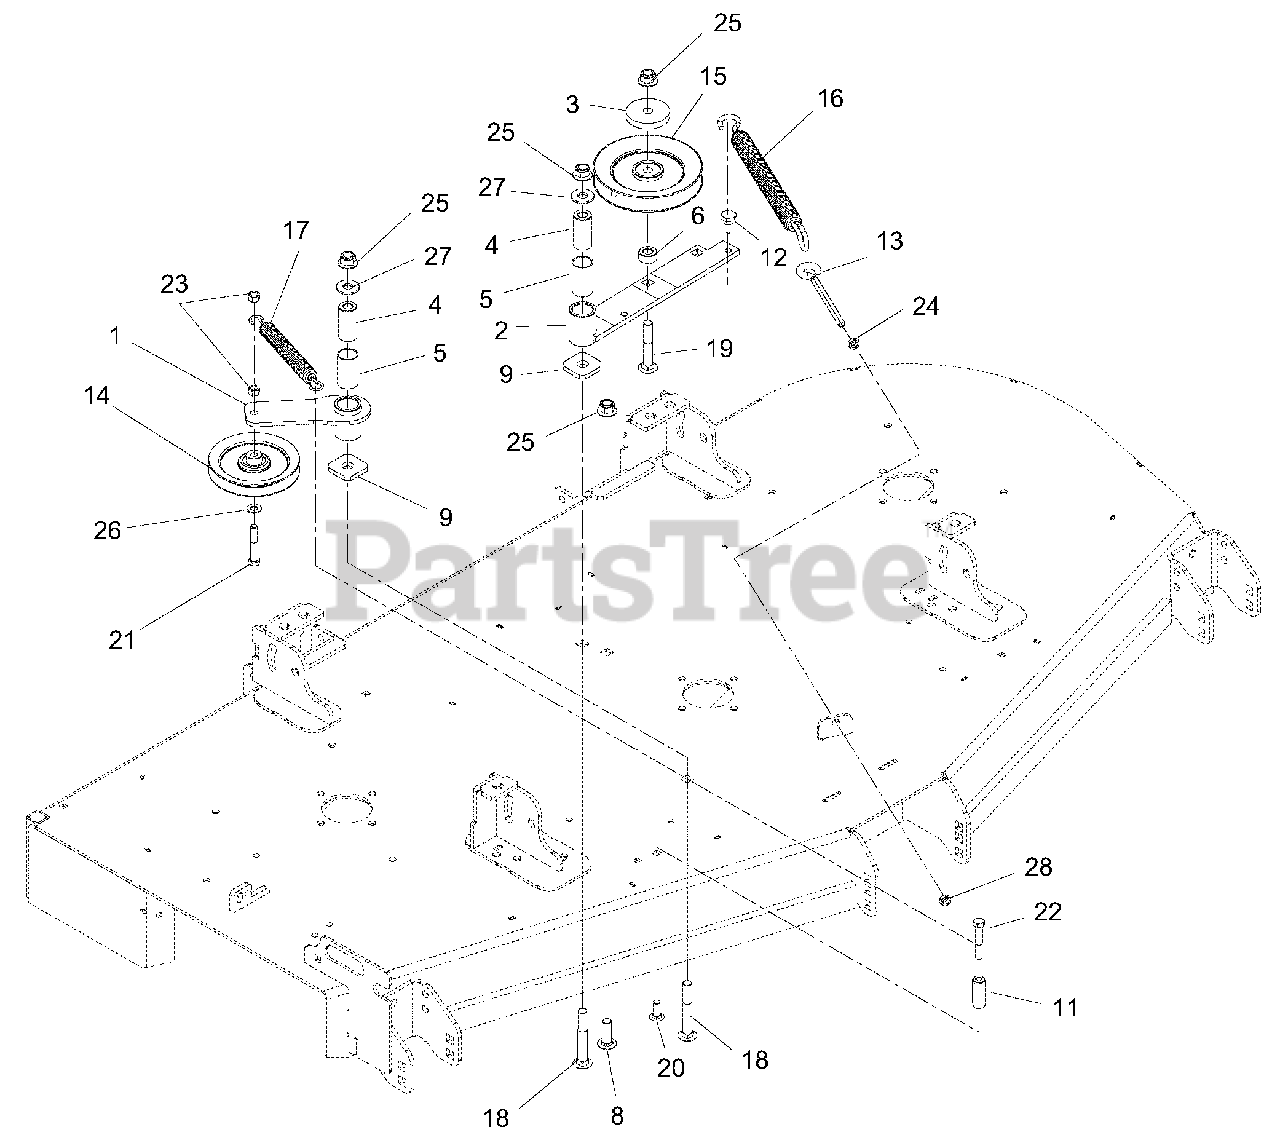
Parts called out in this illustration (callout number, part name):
1	WMT, IDLER PIVOT ARM
2	WMT, IDLER PIVOT ARM
3	CAP, IDLER BEARING SEALING
4	BSHG, SPCR .502X.997X2.03
5	BSHG, 1.00X1.125X1.937
6	BSHG, SPCR .502 X .997.50 PM
8	BLT, RNHDSQSHNK 1/2-13 X 2.00 FULL
9	WSHR, -FLT.640X1.75X.250
11	NUT-HEX COUPLING
12	BLT, SHLDR EP .38-16X.30 HEX
13	BOLT, .38-16X6.00 .62 DIA EYE
14	SHV, .38" ID X 5.0’’ OD V-IDLER
15	SHEAVE, .50" ID X 6.00" OD V-IDLER
16	SPRG, EXTENSION
17	SPRG, EXT. .845 X 6.55
18	BLT-RDHDSQNK .50-13X3.50 G5
19	BLT-RDHDSQNK .50-13X3.00 G5
20	BLT-RDHDSHSQNK.38-16X1.0 G5YZ
21	BLT-HEX .38-16X2.25 GR5 YWZC
22	BLT-HEX .38-16X1.75 GR5 YWZC
23	NUT-LK-CTR .38-16 YWZC
24	NUT, 3/8-16 JAM GR5
25	NUT-LK-NYL-FLG .50-13 YWZC
26	WSHR-FL-STL.406X.812X.065 YWZ
27	WSHR-FL-STL.563X1.38X.109YWZC
28	NUT-LK-CTR JAM .375-16
